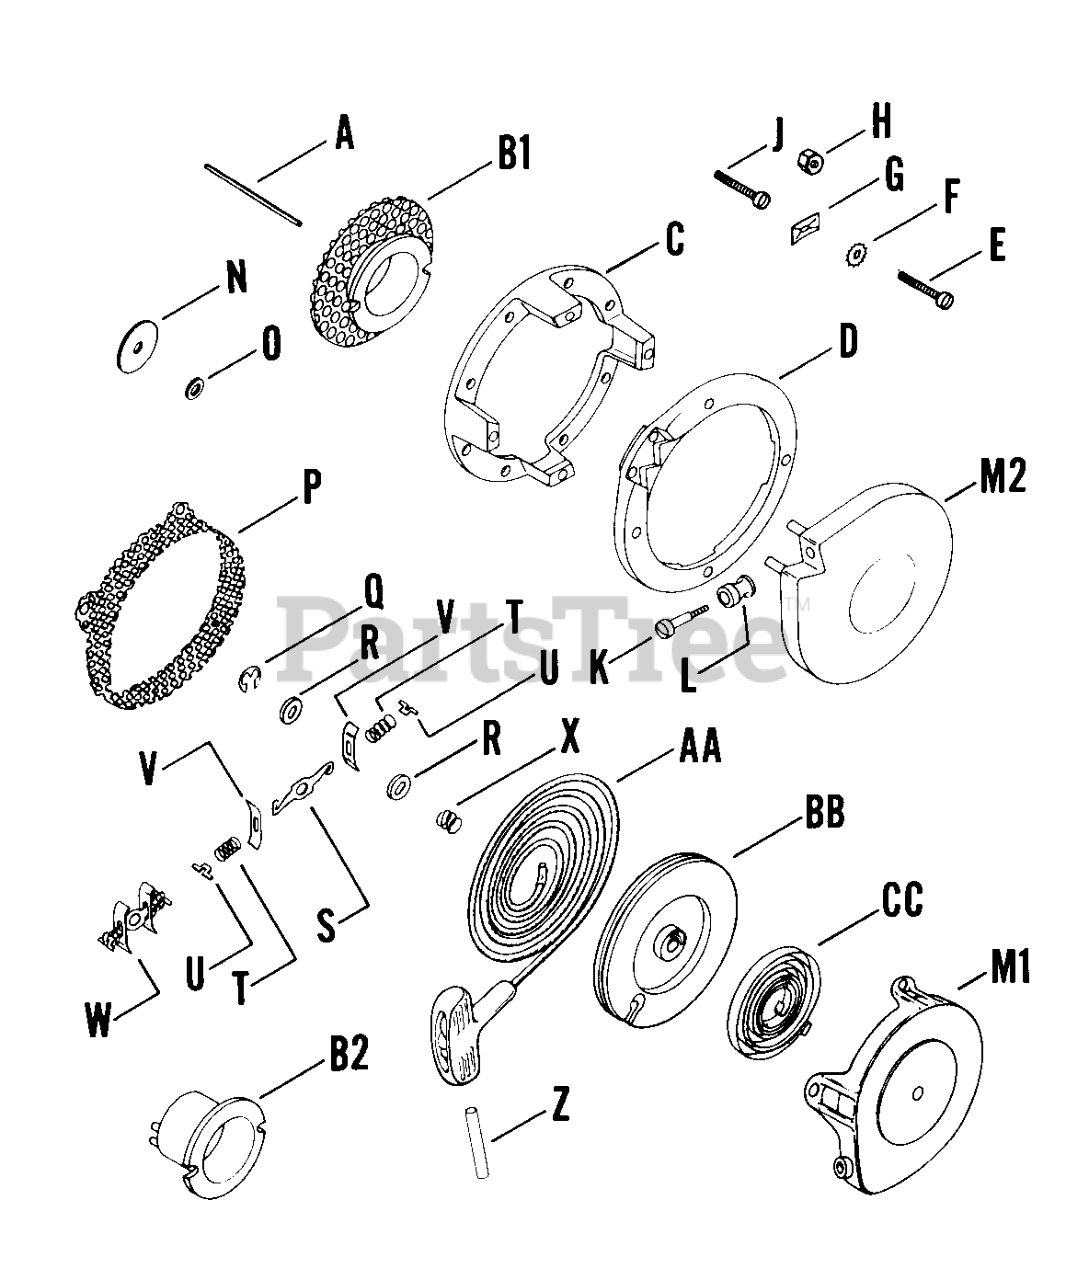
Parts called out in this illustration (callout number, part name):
B-220589	KIT - USE 46 755 02
A	PIN - DISCONTINUED
B1	CUP - DISCONTINUED
M1	COVER - DISCONTINUED
N	WASHER - DISCONTINUED
Q	RING - DISCONTINUED
R	WASHER - DISCONTINUED
W	SHOE - DISCONTINUED
X	SPRING - DISCONTINUED
AA	CORD - DISCONTINUED
BB	ROTOR - DISCONTINUED
